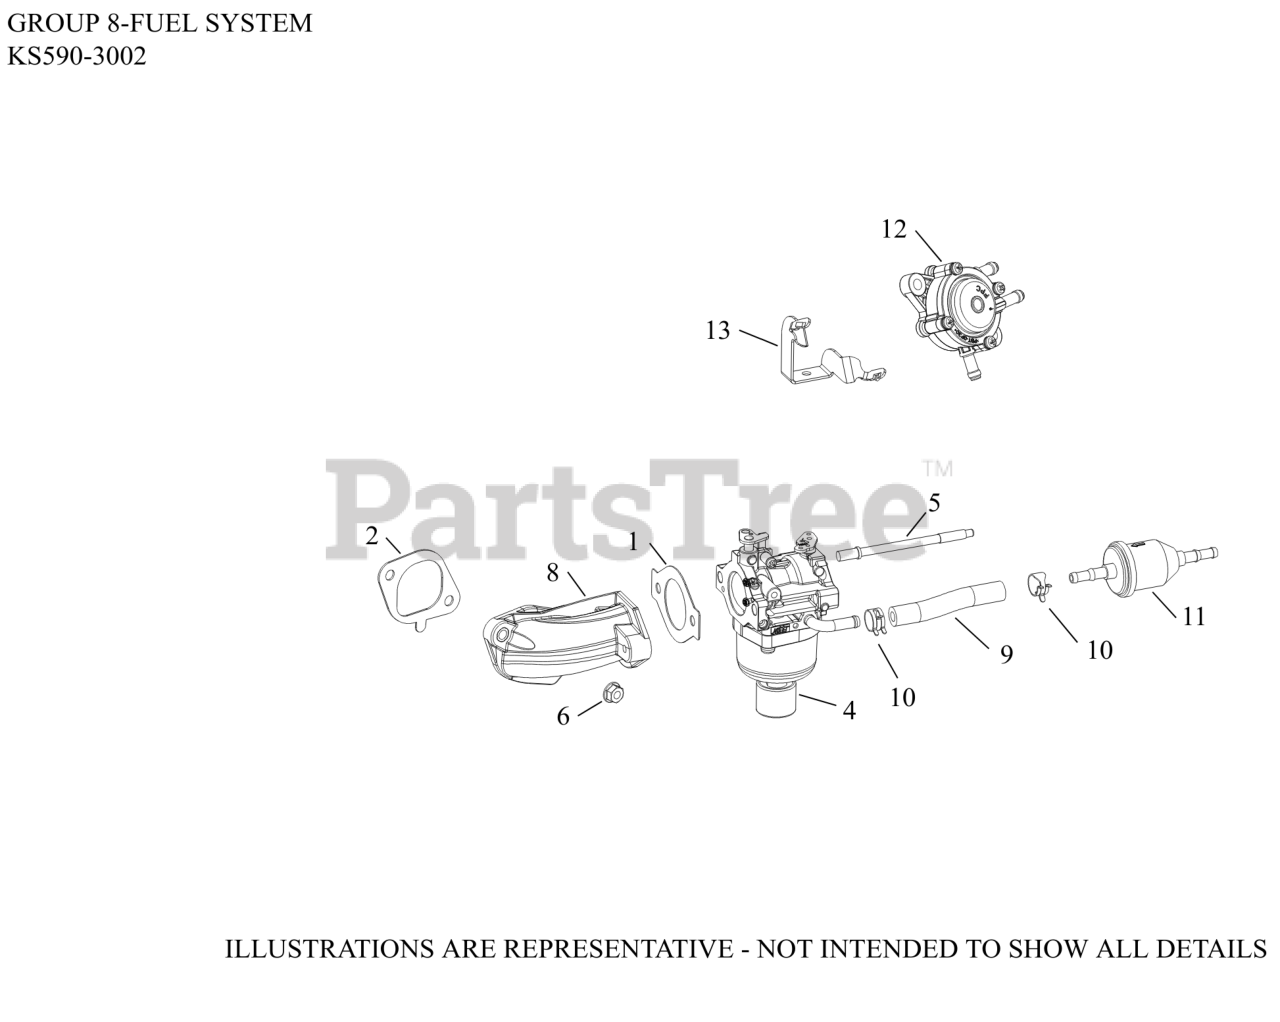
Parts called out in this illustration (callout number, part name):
1	GASKET, CARBURETOR (THROTTLE)
2	GASKET, INTAKE MANIFOLD
4	KIT,CARB(NIKKI)
5	STUD, CARBURETOR
6	NUT, FLG M6X1.0
8	MANIFOLD, INTAKE ASSEMBLY
9	HOSE,LW PERM.FUEL 24.00"-USE 25 111 81-S
10	SPRING CLAMP, HOSE
11	FILTER,FUEL 51 MICRON (FUEL PUMP)
12	PUMP, FUEL (PULSE)-(#2539326S)
13	BRACKET, FUEL PUMP
NI	HIGH ALTITUDE KIT (5000 FT)
NI	KIT, OVERHAUL
NI	KIT, CHOKE SHAFT
NI	KIT, O-RING
NI	KIT, SOLENOID (NIKKI)
NI	KIT, BOWL WITH O-RINGS
NI	KIT, FLOAT & INLET NEEDLE FOR FUEL PUMP
NI	KIT, THROTTLE SHAFT
